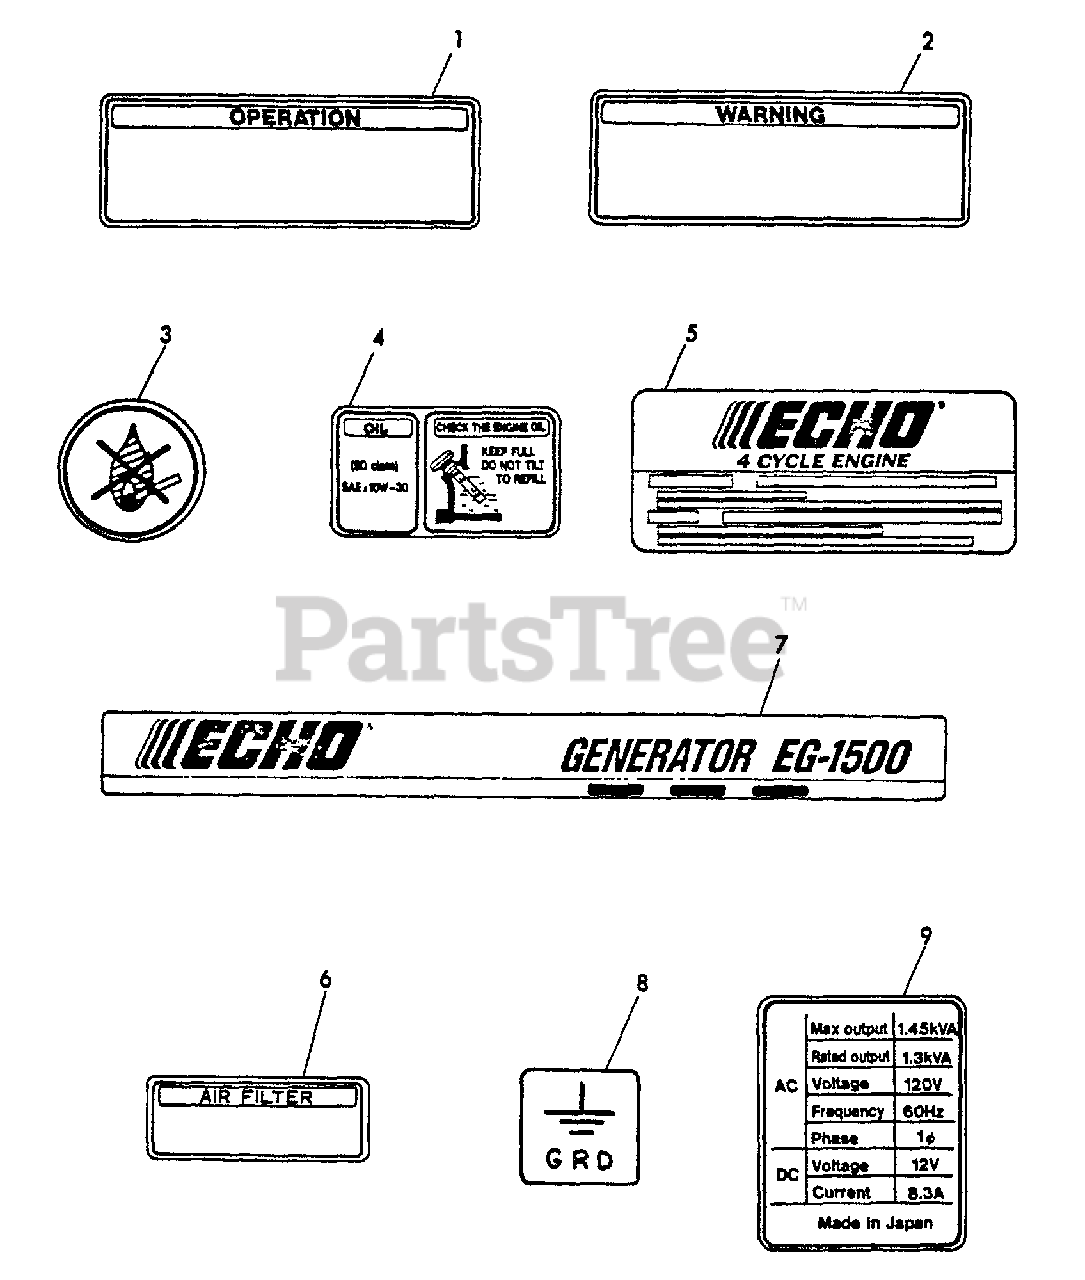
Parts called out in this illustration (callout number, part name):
1	LABEL - OPERATION
2	LABEL - WARNING
3	LABEL - NON FIRE
4	LABEL - OIL
5	LABEL - ECHO
6	LABEL - AIR CLEANER
7	LABEL - MODEL EG1500
8	LABEL - GROUND
9	LABEL - GENERATOR
